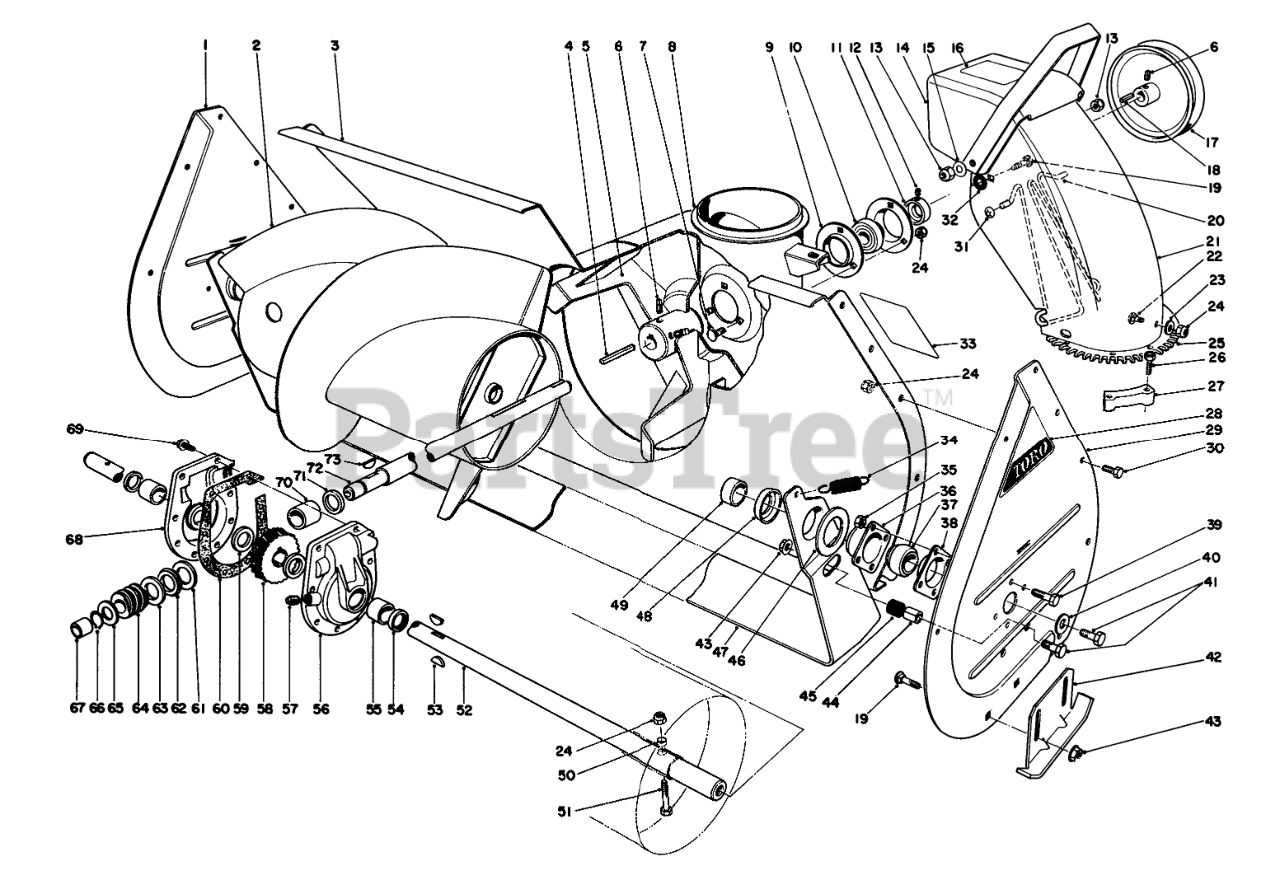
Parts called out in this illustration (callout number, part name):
1	RH AUGER SIDE PLT R
2	LH AUGER WA 32" B
3	AUGER HSG WA 32" R
5	IMPELLER ASM
6	SCREW-SET, SQH
7	BOLT-CARR
8	CHUTE RING
9	BRG FLANGE
10	BALL BRG W/COLLAR
11	EXT LOCKING COLLAR
12	SCREW-HSH
13	NUT-LOCK, CONE
14	Deflector (Incl. Ref. #16)
15	WASHER-BELLEVILLE
16	Decal-Danger
17	1/2 X 9.5 DIA PULLEY
18	SQUARE KEY
19	SCREW-CARR
20	CHUTE WIRE
21	Chute-Upper
22	SCREW-CARR
23	WASHER-PLAIN
24	NUT-LOCK, NI
25	Screw
26	SCREW-SPECIAL
27	RETAINER-CHUTE
28	AUGER SIDE PLT DECAL
29	LH AUGER SIDE PLT R
30	SCREW-HH
31	NUT-PUSH
32	WASHER-RUBBER
33	DECAL-WARNING, AUGER
34	SPRING-TENSION
35	NUT-LOCK, CONE
36	BEARING-FLANGE, FRONT
37	BEARING
38	BEARING-FLANGE, REAR
39	SCREW-HH
40	WASHER
41	SCREW-HH
42	AUGER SKID WA R
43	NUT-HF
44	SCRAPER STOP SPACER
45	SCRAPER STOP CUSHION
46	SCRAPER BLADE SPACER
47	SCRAPER BLADE 32" R
48	Positioner-Scraper
49	AUGER SPACER
50	SPACER-HUB, AUGER
51	Auger Bolt
52	32 AUGER SHAFT
53	KEY-WOODRUFF
54	SEAL-OIL
55	BUSHING
56	Gear Case L.H. (Incl. Ref. #54-55)
57	PLUG-PIPE, SQH
58	GEAR-WORM, 27T
59	WASHER-THRUST
60	GASKET-CASE, GEAR
61	WASHER-THRUST
62	BEARING-THRUST
63	THRUST-WASHER
65	WASHER-THRUST
66	Ring-Snap
67	BUSHING
68	Gear Case R.H. (Incl. Ref. #54-55)
69	SCREW-TAPTITE
70	BUSHING-SPECIAL
71	RING-QUAD
72	SHAFT-IMPELLER
73	KEY-WOODRUFF
